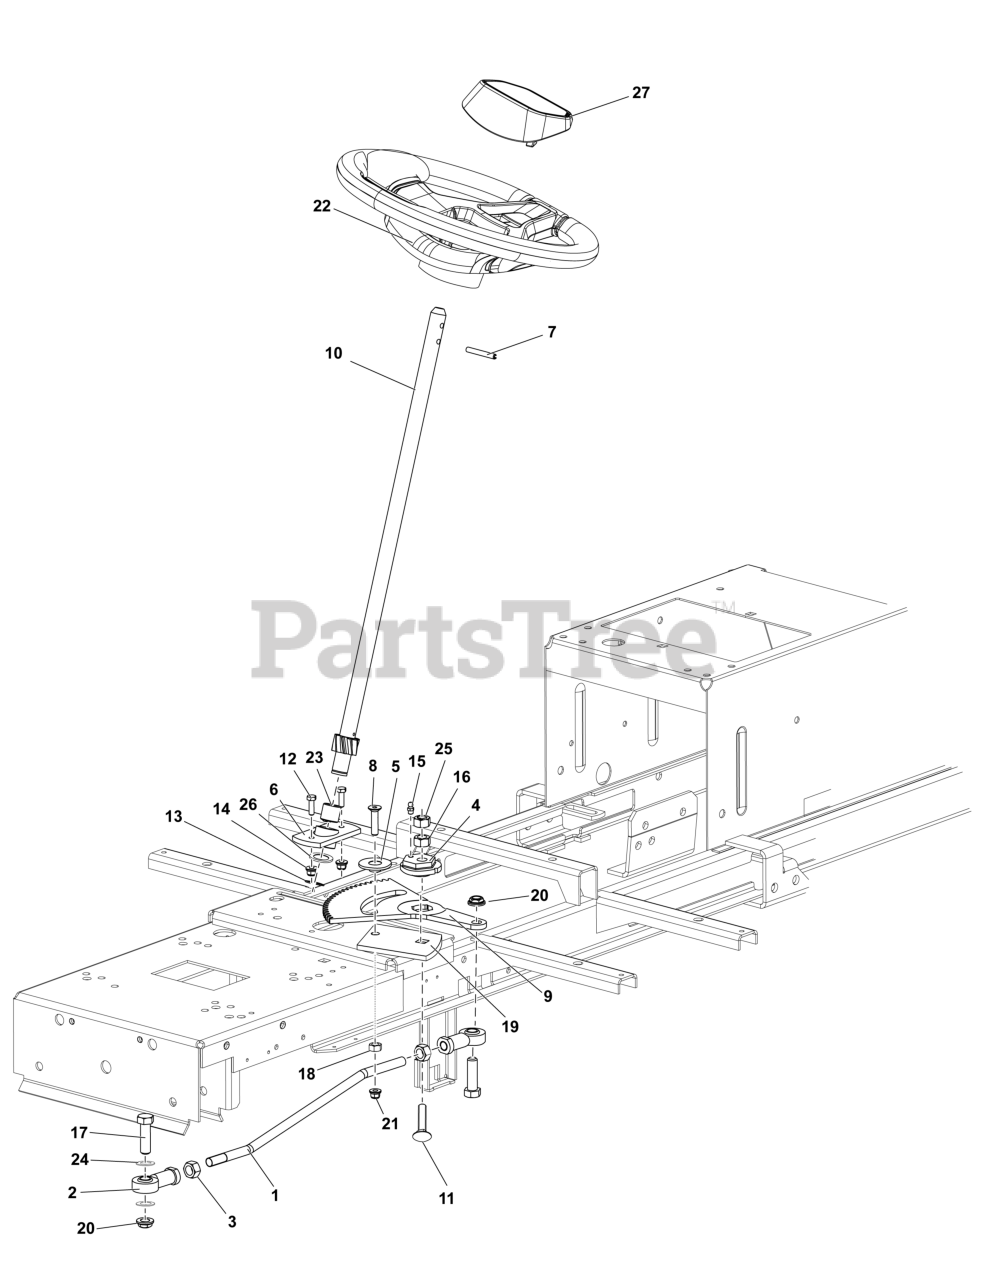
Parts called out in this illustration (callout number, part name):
2	JOINT, Ball
4	ECCENTRIC
9	TOOTHED SEGMENT
15	ZERK, Grease Fitting
22	WHEEL, Steering
27	CAP, Steering Wheel
